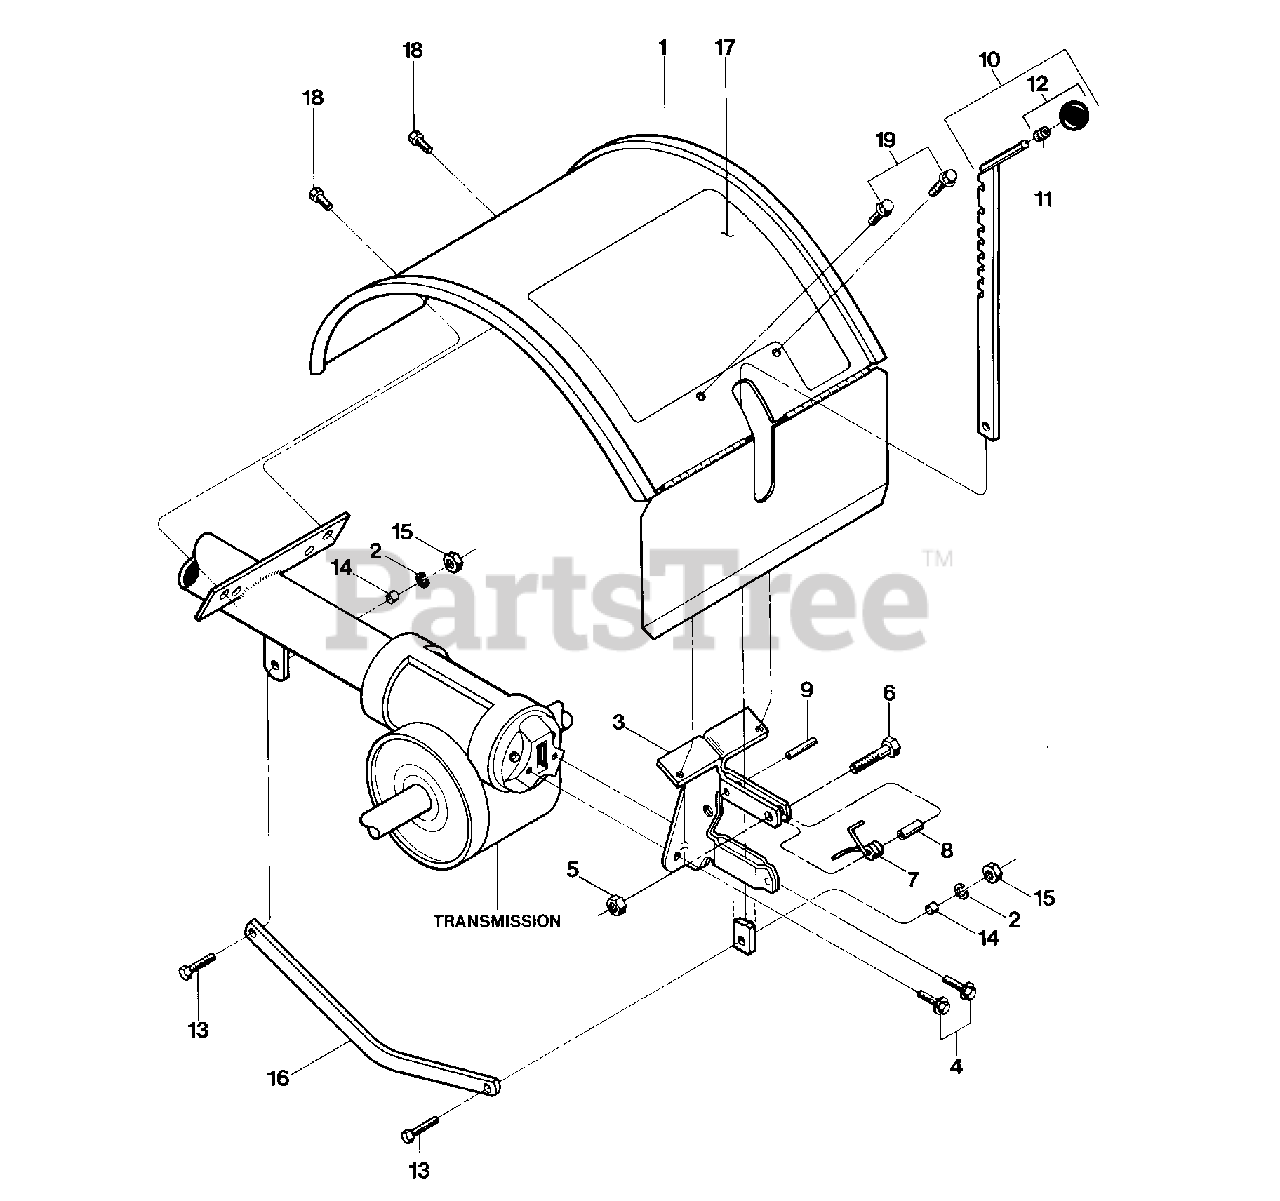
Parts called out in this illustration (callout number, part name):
1	Tine Hood
2	Lockwasher, 3/8
3	Bracket-hood & depth regulator
4	Hex Flange Screw, 5/16-18 x 5/8
5	Hex Locknut, 1/4-20
6	Hex Hd. Screw, 1/4-20 x 1
7	Spring
9	Roll Pin (spiral), 1/4 x 1
10	Depth Adjustment Bar Assembly
11	Retaining Ring (tolerance ring)
12	Knob, Depth Regulator
13	Hex Hd. Screw, 3/8-16 x 1-1/4
14	Bushing, Drag Bar
15	Hex Nut, 3/8-16
16	Drag Bar
17	Decal, operating instructions
18	Hex Hd. Screw, self-tapping, 5/16-18 x 1/2
19	Hex Flange Screw, self-tapping, 1/4-20 x 1/2
